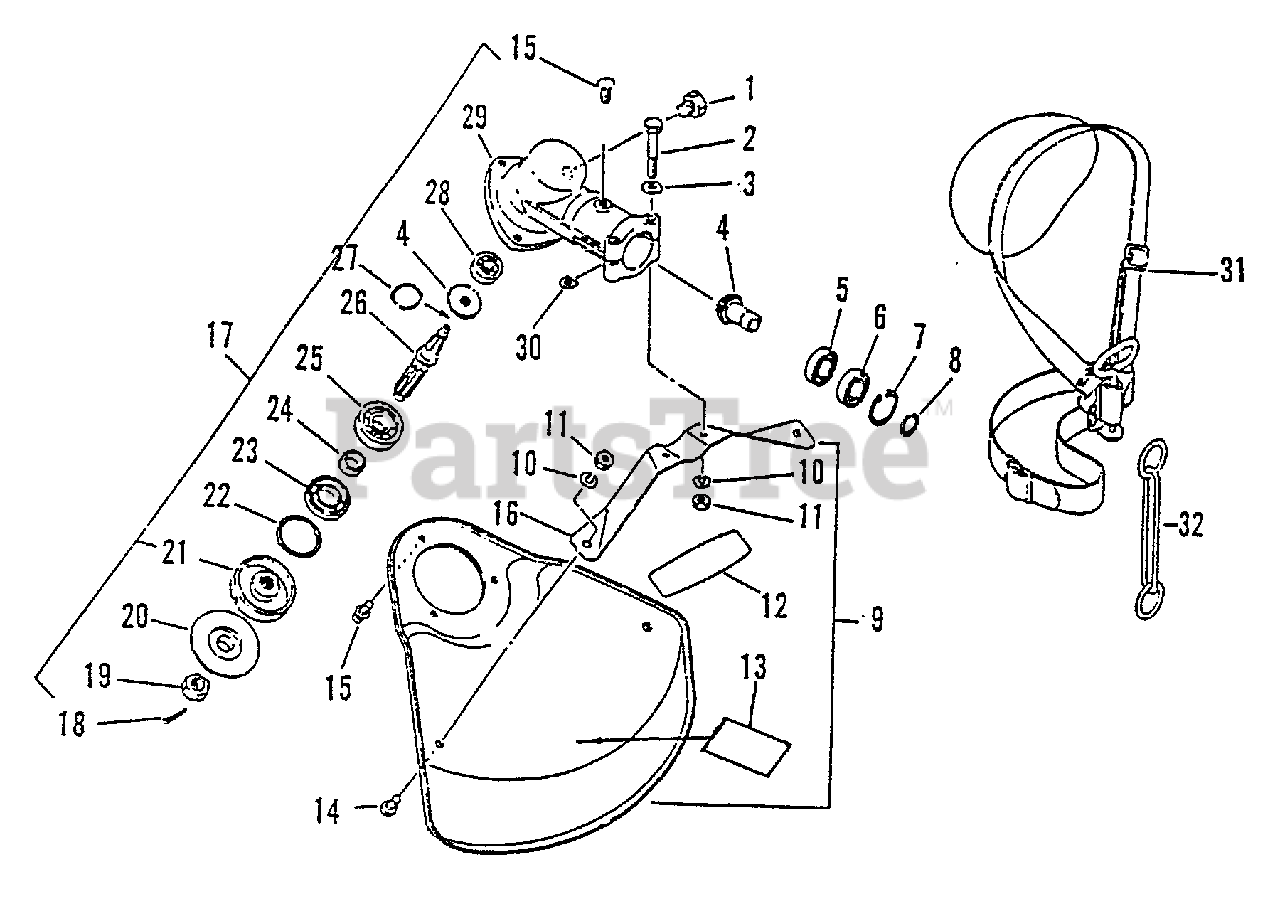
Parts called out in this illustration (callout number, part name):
1	BOLT 8×8 SP
2	BOLT 5×35 SP
3	WASHER, FLAT 5.5×10×0.8
4	GEAR SET
5	BEARING, BALL 6900
6	BEARING, BALL 6900Z
7	RING, SNAP Ø22
8	RING, SNAP Ø12
9	SHIELD ASSY
10	WASHER, SPRING 5
11	NUT M5
12	LABEL, ECHO
13	LABEL - CAUTION
14	SCREW 5×8
15	SCREW 5×10
16	BRACKET, SHIELD MOUNTING
17	GEAR CASE ASSY
18	PIN, COTTER 2×22
20	PLATE, ADAPTOR - LOWER
21	PLATE, ADAPTER - UPPER
22	RING, SNAP Ø32
23	SEAL, OIL 22
24	SPACER 11.8×15×9
25	BEARING, BALL - 6201 C3
26	SHAFT, GEAR
27	RING, SNAP Ø10
28	BEARING, BALL 609
29	HOUSING, GEAR CASE
31	SHOULDER STRAP ASSY
32	HOOK
